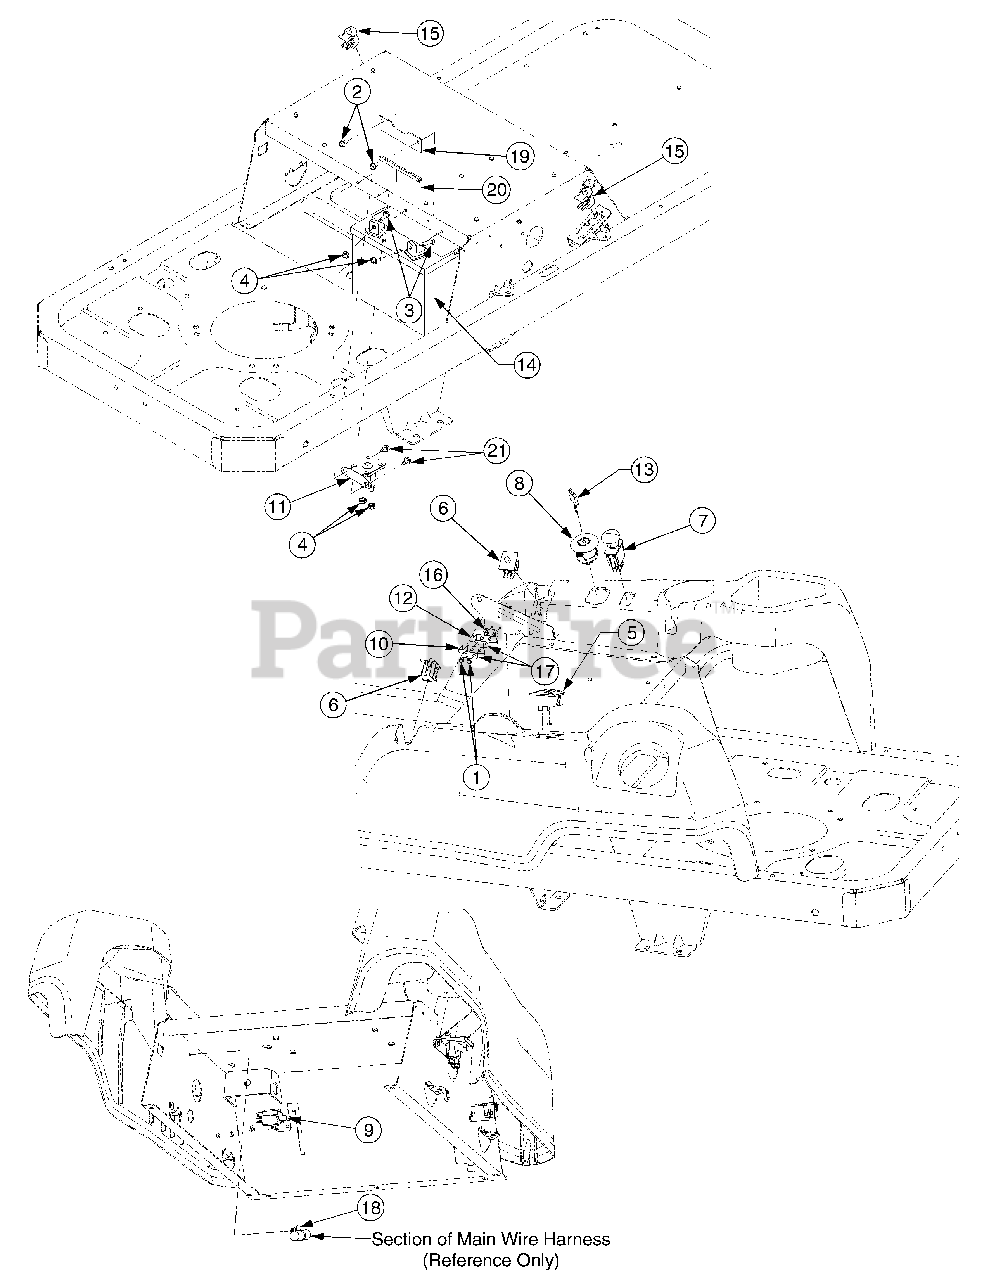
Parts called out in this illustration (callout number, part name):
1	Screw, Hex Wash. Hd. Tapp #8-18 x .5
2	Screw, Hex Wash. Hd. Tapp, 1/4-20 x .5
3	Screw, Hex Cap, 1/4-20 x .75 GR5 ..
4	Nut, Hex Sems, 1/4-20
5	Meter, Hour
6	Switch, Dbl. Pole - Neutral
7	Switch, PTO
8	Switch, Ignition
9	Switch, 3-Pole, (NC-NO-NO) - Brake
10	Switch, Outer Seat Spring
11	Solenoid
12	Switch, Inner Seat Spring
13	Key
14	Battery, 235 CCA
15	Switch, Snap Mount (N.C.) - Reverse
16	Plate, Insulator Boss
17	Plate, Insulator
18	Tie, Cable
20	Strip, Trim 4.5in
21	Screw, Hex Wash. Hd. Tapp, 1/4-20 x .375
